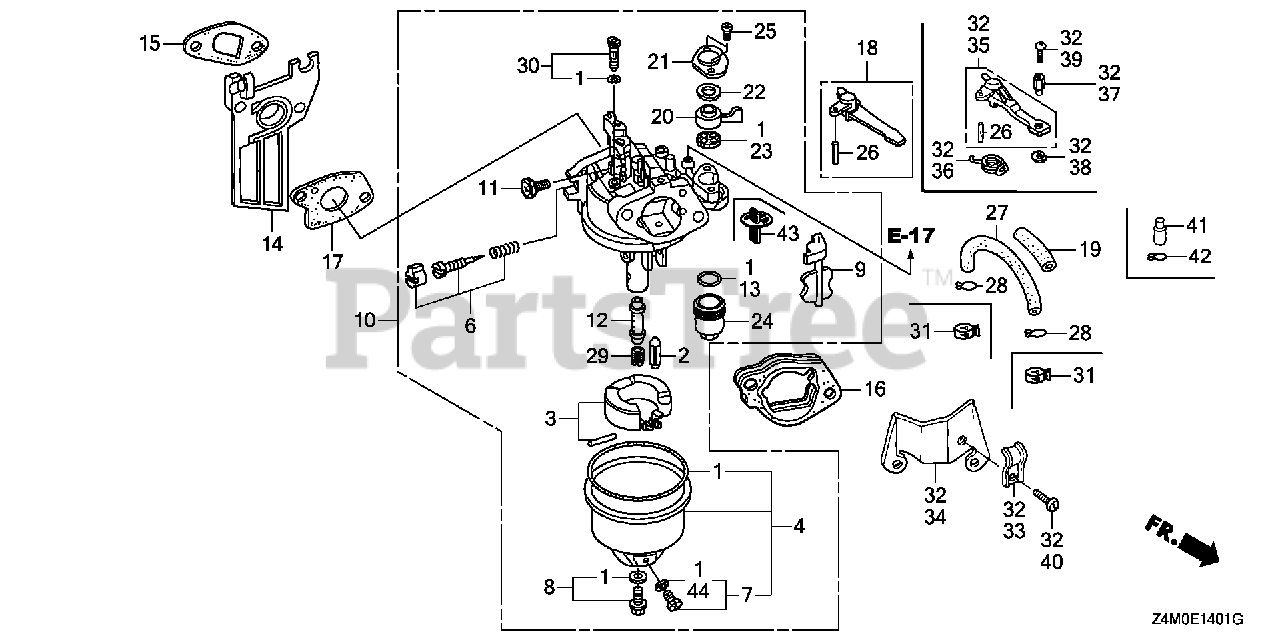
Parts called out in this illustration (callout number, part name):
1	GASKET SET
2	VALVE SET, FLOAT (CARBURETOR NO.) (SEAT NOT INCLUDED)
3	FLOAT SET
4	CHAMBER SET, FLOAT (CARBURETOR NO.)
6	SCREW SET (Honda Code 4219879). (CARBURETOR NO.)
7	SCREW SET, DRAIN (Honda Code 1672187). (CARBURETOR NO.)
8	SCREW SET
9	CHOKE SET
10	CARBURETOR ASSY. (BE65Q A)
11	SCREW, THROTTLE STOP
12	NOZZLE, MAIN
13	GASKET, FUEL STRAINER CUP
14	INSULATOR, CARBURETOR
15	GASKET, INSULATOR
16	SPACER, CARBURETOR
17	GASKET, CARBURETOR
18	LEVER, CHOKE (STD)
20	LEVER, VALVE
21	PLATE, LEVER SETTING (CARBURETOR NO.)
22	SPRING, PETCOCK LEVER (CARBURETOR NO.)
23	GASKET, VALVE
24	CUP, FUEL STRAINER
25	SCREW, PAN (3X6)
26	PIN, SPRING (2X12)
29	JET, MAIN (#65)
29	JET, MAIN (#68)
29	JET, MAIN (#70)
30	JET SET, PILOT (#35)
44	WASHER, PLAIN (6.2X10.7 DRAIN) (CARBURETOR NO.)
